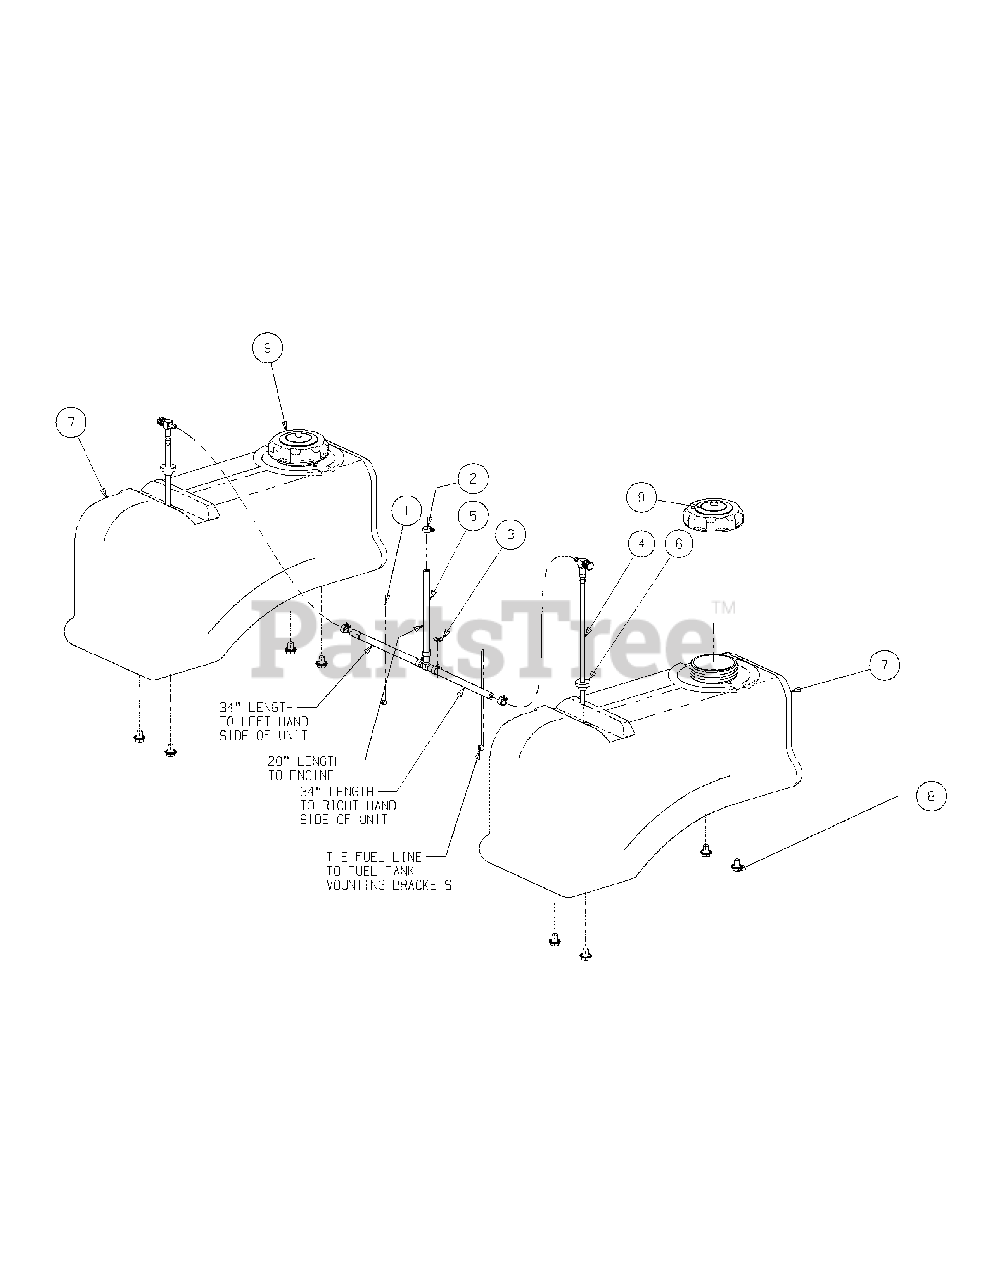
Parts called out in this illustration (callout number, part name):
1	Cable Tie
2	Hose Clamp, SAE #4: 1/4-5/8, SS
3	Flat Washer, 1.4 x .630 x .0515
4	Fuel Fitting
5	Fuel Hose Assembly includes:
5	Hose, 1/4" Fuel Line
5	Clamp, Union
5	Tee Fitting, Fuel
6	Grommet, Fuel Tank
7	Fuel Tank
8	Hex Cap Screw, 3/8-16 x .50 Flange Whiz
9	Fuel Cap, 3.5
